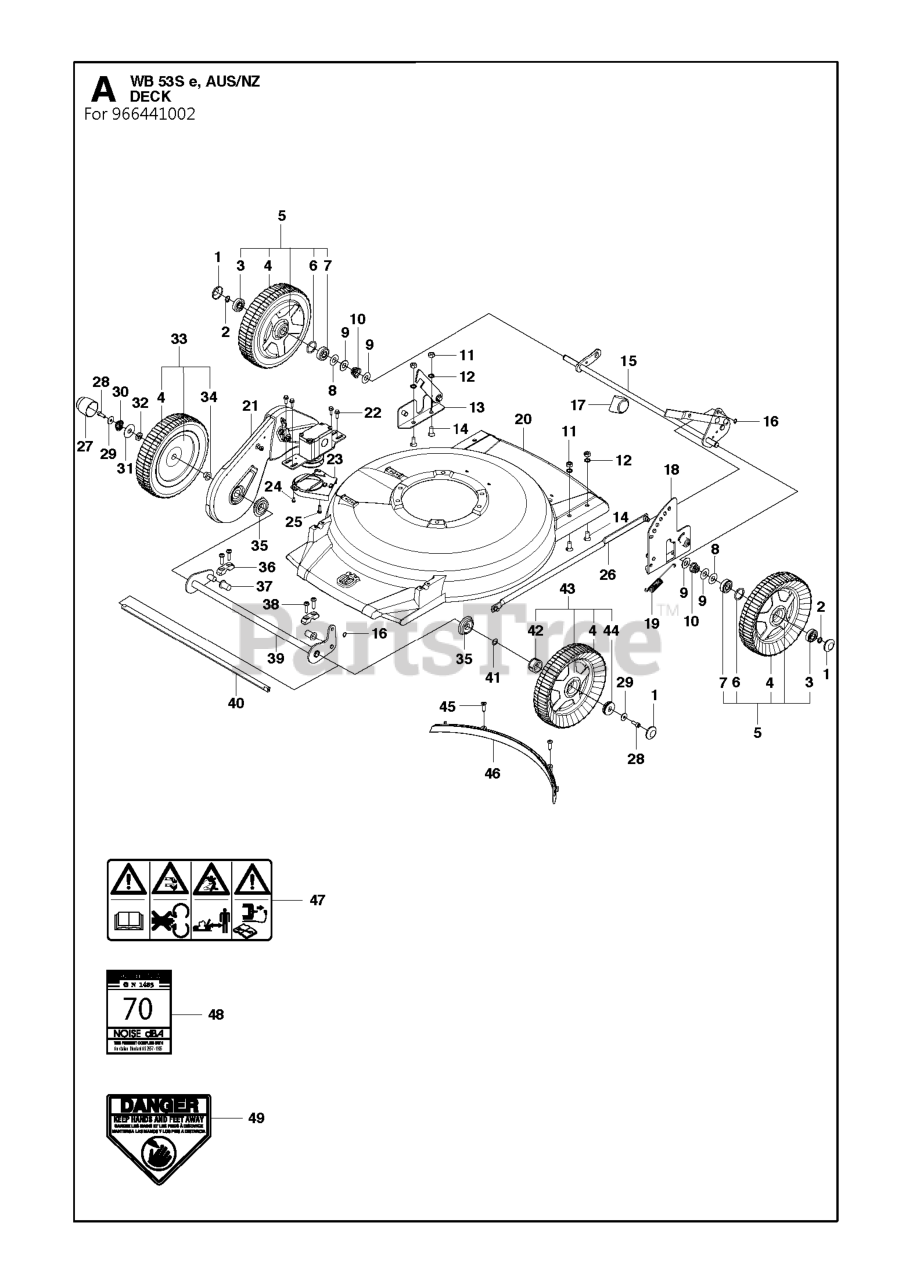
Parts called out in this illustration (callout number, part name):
11	NUT
16	RETAINING RING SGA 8
49	LABEL, DANGER
